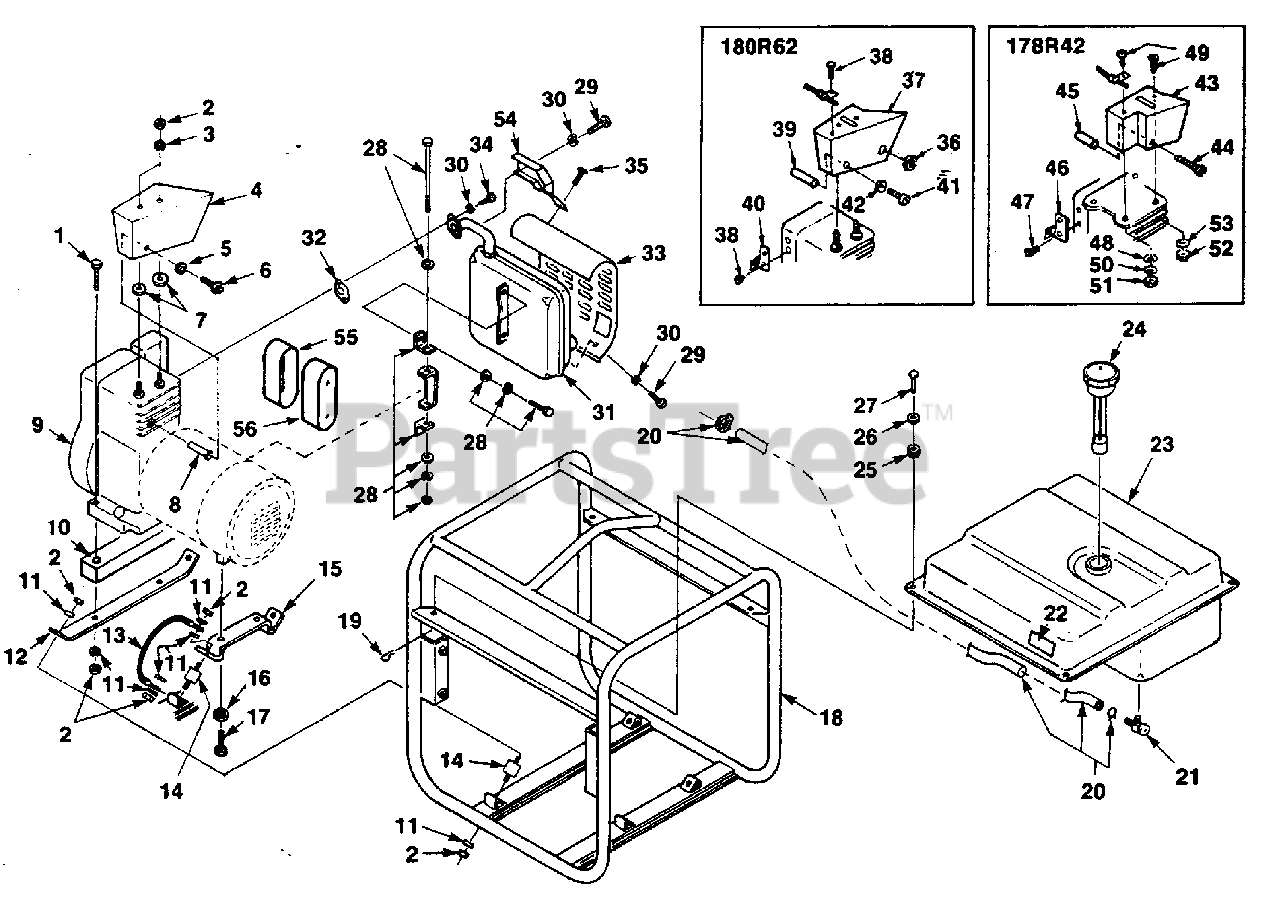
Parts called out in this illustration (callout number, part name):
1	SCREW Hex hd. 5/16-18 x 2 1/2 2
2	NUT-Hex 5/16-18
5	WASHER-Flat #10
6	SCREW Mach Rd. Hd. 10-24 x 1 1/2
7	WASHER-Flat
11	WASHER-Int. Lock 5/16
12	SUPPORT-Engine
13	GROUND STRAP
14	VIBRATION ISOLATOR
15	SUPPORT-Generator
16	WASHER-Lock Int.
17	SCREW- Thread Forming
18	ROLL CAGE
19	PIN-Cotter
20	FUEL LINE ASSEMBLY
21	FUEL VALVE
22	DECAL-I.D.
23	FUEL TANK
24	FUEL CAP
25	GROMMET-Isolator
26	WASHER-Flat
27	PIN-Clevis
43	DEFLECTOR-Air
44	SCREW-Hex hd
46	BRACKET-Lite
47	SCREW #8-18 x 3/8
48	WASHER-Flat- 1/4
49	SCREW-Cap hex 1/4-20 x 1"
50	WASHER-Lock 1/4"
51	NUT-Hex 1/4-20
52	NUT-Hex 5/16-18
